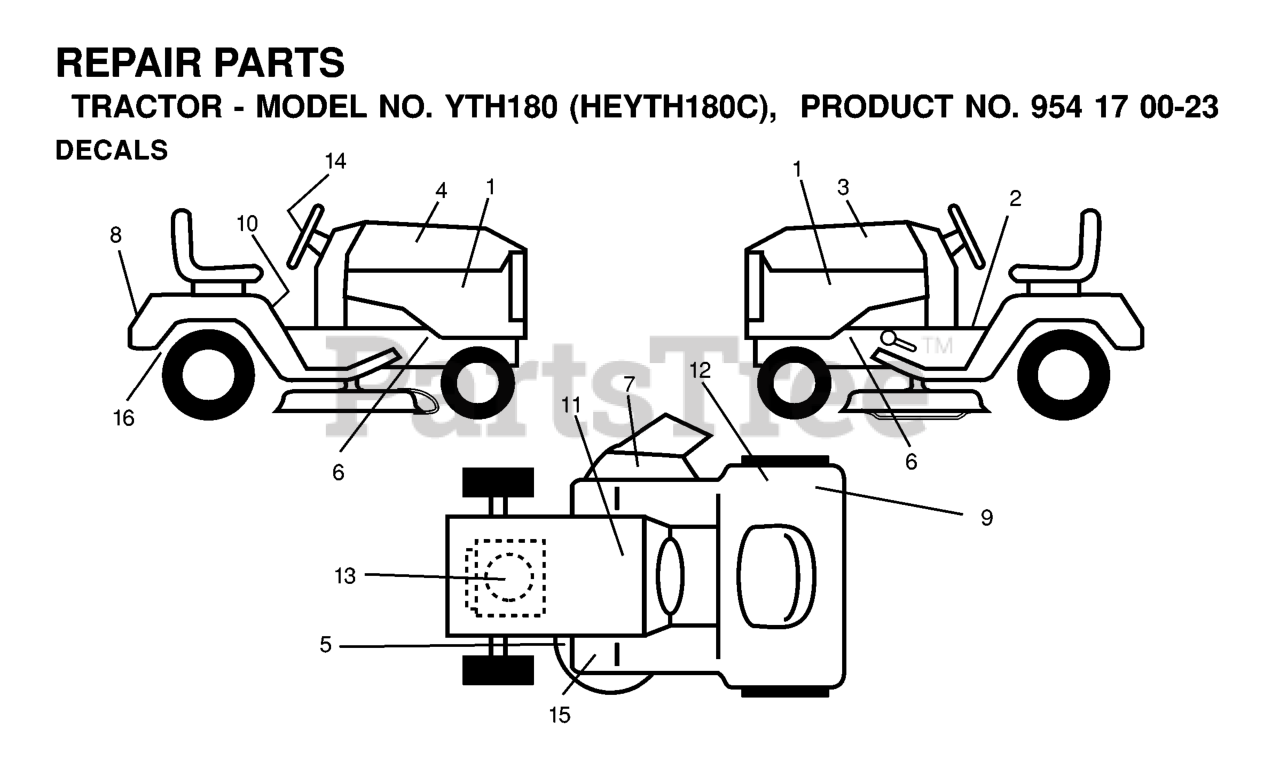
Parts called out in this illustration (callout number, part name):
1	DECAL PNL SIDE
2	DECAL PARK BRAKE
3	DECAL L.H. YTH180
4	DECAL R.H. YTH180
5	DECAL V BELT SCHEMATIC
7	DECAL MOWER CUT/FINGER
8	DECAL FENDER HUSQ
9	DECAL CERTIFICATION
10	DECAL READ OWNER'S MAN SYMS
11	DECAL BTRY SYMBOLS
12	DECAL EUROPE STANDARD CE
14	DECAL.WHEEL.STEERING.HUSQ.PERM
15	DECAL
16	DECAL
